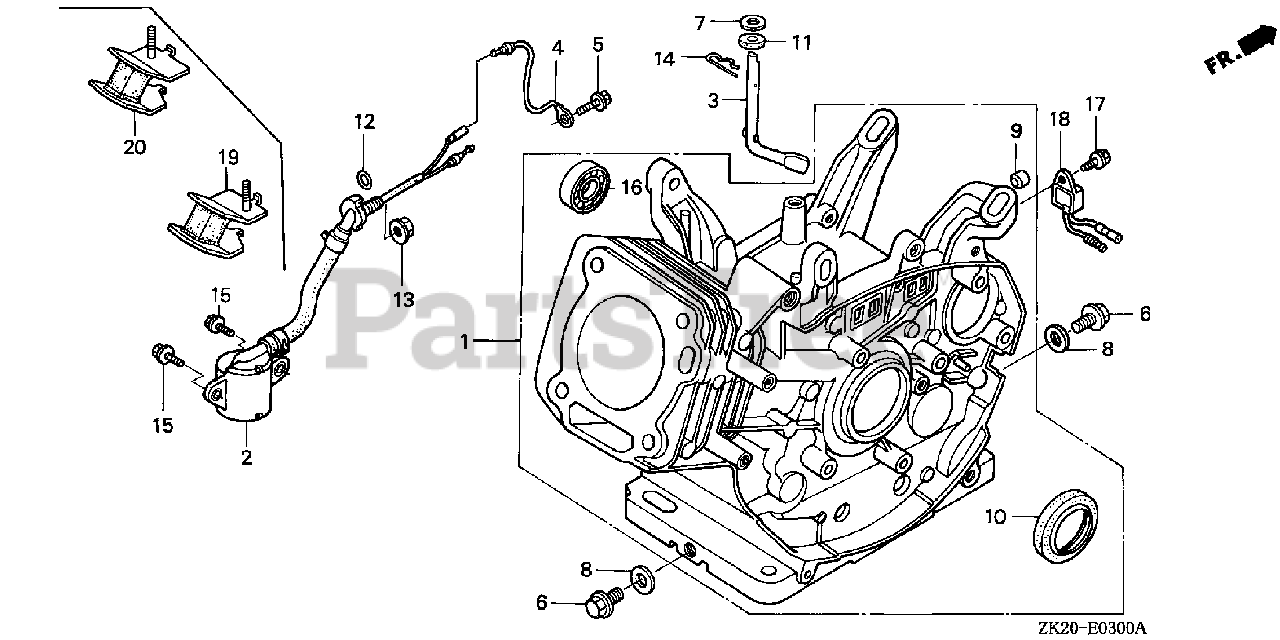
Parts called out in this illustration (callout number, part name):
1	CYLINDER ASSY. (BALANCER+OIL ALERT)
2	SWITCH ASSY., OIL LEVEL
3	SHAFT, GOVERNOR ARM
4	SUB-HARNESS
5	BOLT, FLANGE (6X12) (CT200)
6	BOLT, DRAIN PLUG
7	WASHER (8.2X17X0.8)
8	WASHER, DRAIN PLUG (12MM)
10	OIL SEAL (30X46X8)
12	O-RING (13.5X1.5) (ARAI)
13	NUT, FLANGE (10MM)
14	PIN, LOCK (10MM)
15	BOLT, FLANGE (6X12)
16	BEARING, RADIAL BALL (6202)
17	BOLT, FLANGE (6X12) (CT200)
18	ALERT UNIT, OIL
